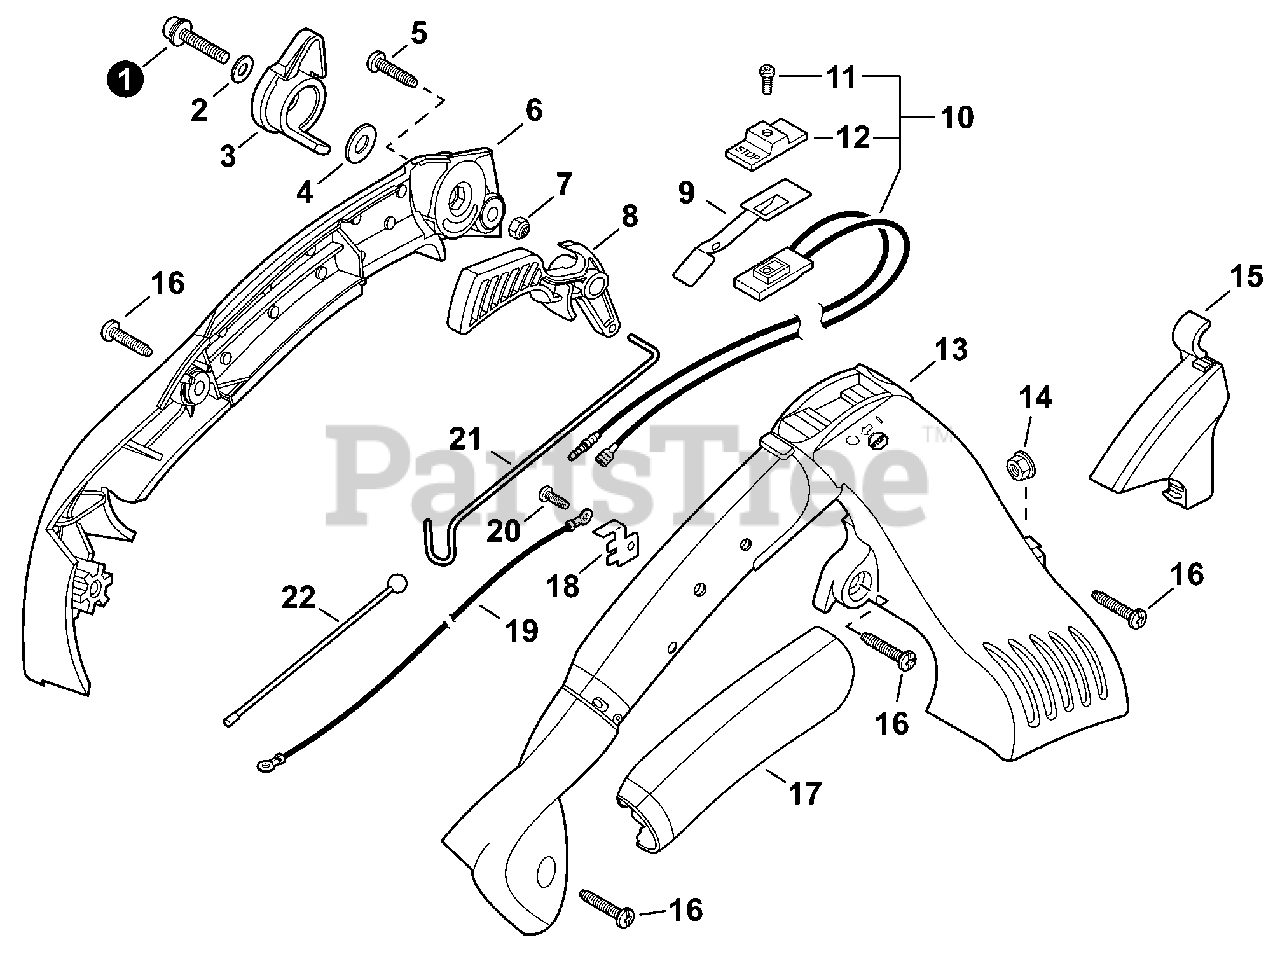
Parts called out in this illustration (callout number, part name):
1	SCREW 5×25
2	WASHER 5.3×10×1
3	LEVER, THROTTLE
4	WASHER 5.5×12×0.8
5	SCREW 5×25
6	HANDLE, CONTROL - LEFT
7	NUT, LOCK M5
8	TRIGGER, THROTTLE
9	TERMINAL
10	SWITCH ASSY, ON-OFF
11	SCREW 3×10
12	KNOB, SWITCH - ORANGE
13	HANDLE, CONTROL - RIGHT
14	NUT, FLANGE M5
15	COVER, THROTTLE
16	SCREW, TAPPING 5×20
17	GRIP, HANDLE
18	TERMINAL, GROUND
19	LEAD - GROUND
20	SCREW 4×10
21	ROD, THROTTLE
22	CABLE, THROTTLE
